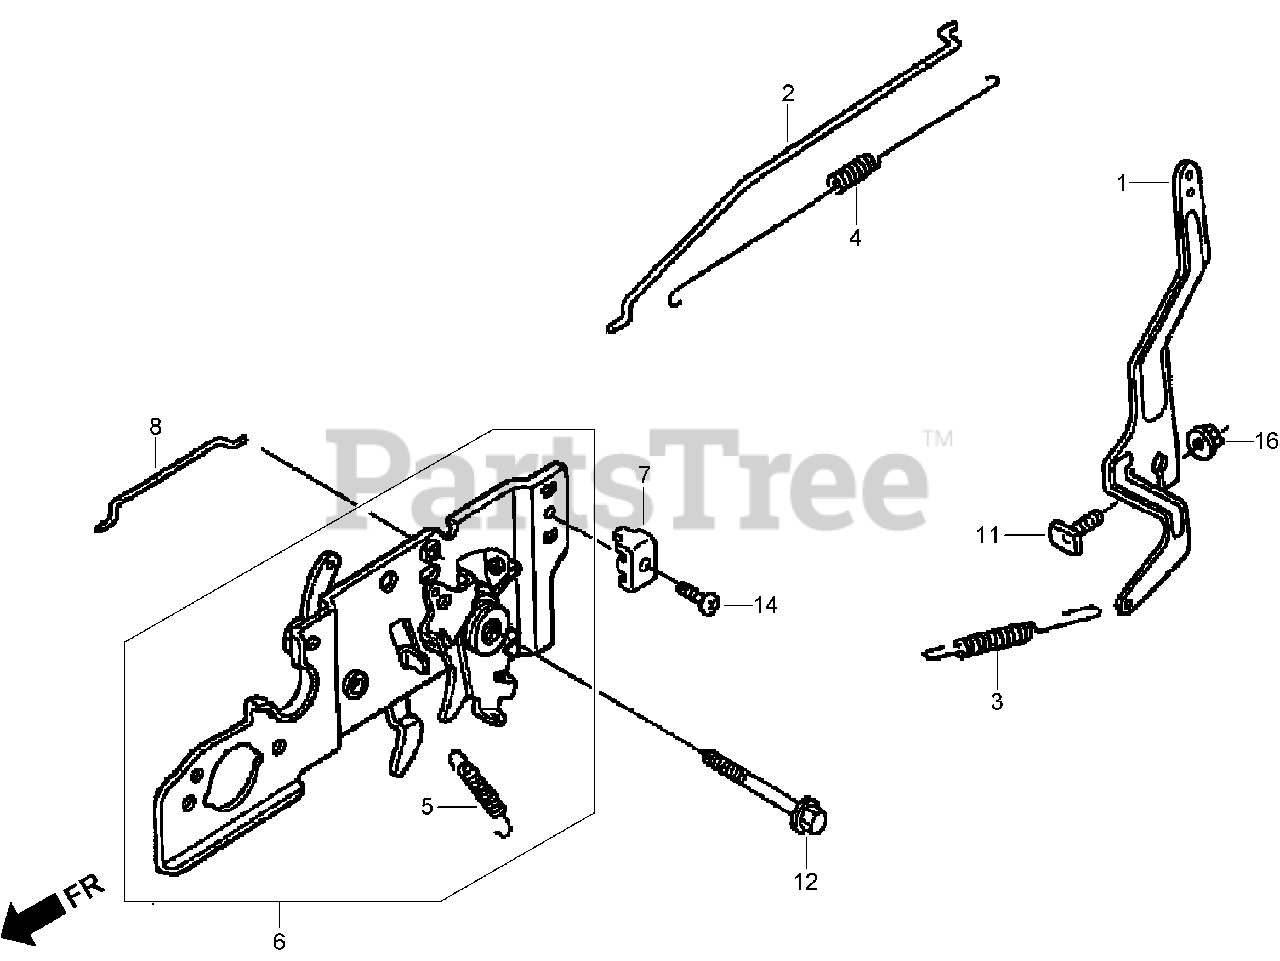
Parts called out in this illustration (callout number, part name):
1	ARM-GOVERNOR
2	ROD-GOVERNOR
3	SPRING-GOVERNOR
4	SPRING-RETURN, THROTTLE
5	Spring-Lever
6	BASE, CONTROL
7	HOLDER-CABLE
8	ROD-CHOKE
11	BOLT-ARM, GOVERNOR
12	BOLT-FLANGE (6X45) (CT200)
14	Screw-Pan (5X16)
16	NUT-FLANGE (6 mm)
